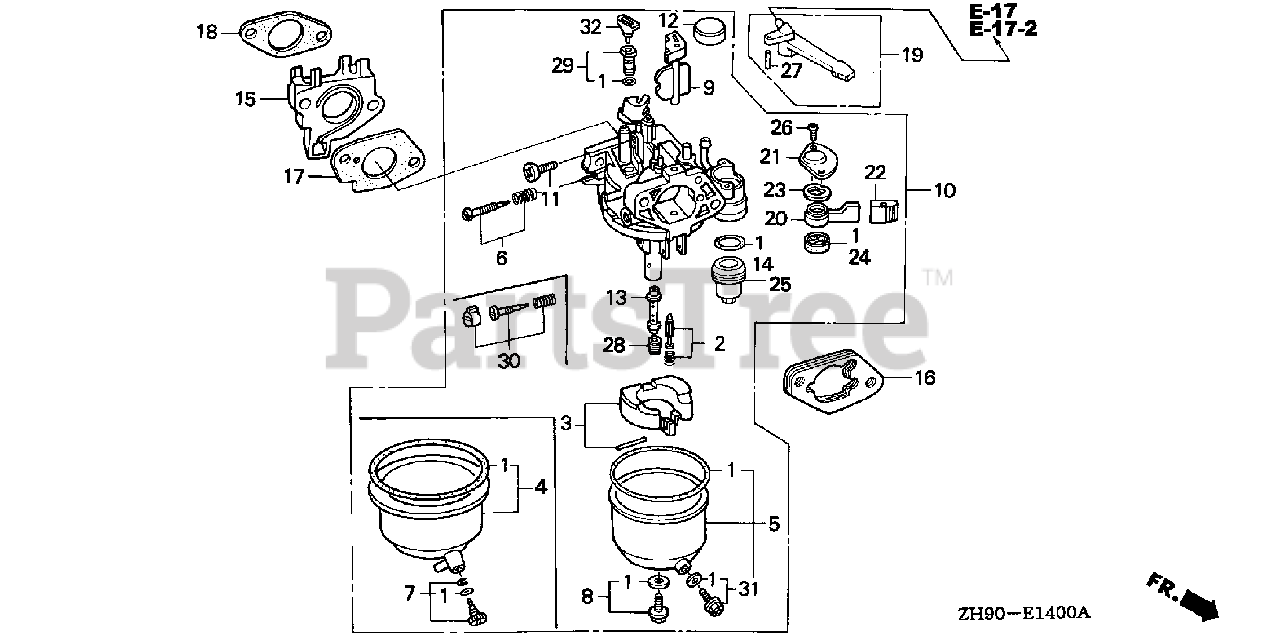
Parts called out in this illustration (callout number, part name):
1	GASKET SET
2	VALVE SET, FLOAT
3	FLOAT SET
5	CHAMBER SET, FLOAT
8	SCREW SET B
9	CHOKE SET
10	CARBURETOR ASSY. (BE75B B)
11	SCREW, THROTTLE STOP
13	NOZZLE, MAIN
14	GASKET, FUEL STRAINER CUP
15	INSULATOR, CARBURETOR
16	SPACER, CARBURETOR
17	GASKET, CARBURETOR
18	GASKET, INSULATOR
19	LEVER, CHOKE (STD)
20	LEVER, VALVE
21	PLATE, LEVER SETTING
23	SPRING, VALVE LEVER
24	GASKET, VALVE
25	CUP, FUEL STRAINER
26	SCREW, PAN (3X6)
27	PIN, SPRING (2X12)
28	JET, MAIN (#80)
28	JET, MAIN (#82)
28	JET, MAIN (#85)
29	JET SET, PILOT (#40)
30	SCREW SET
31	SCREW SET, DRAIN
32	COLLAR, SET
